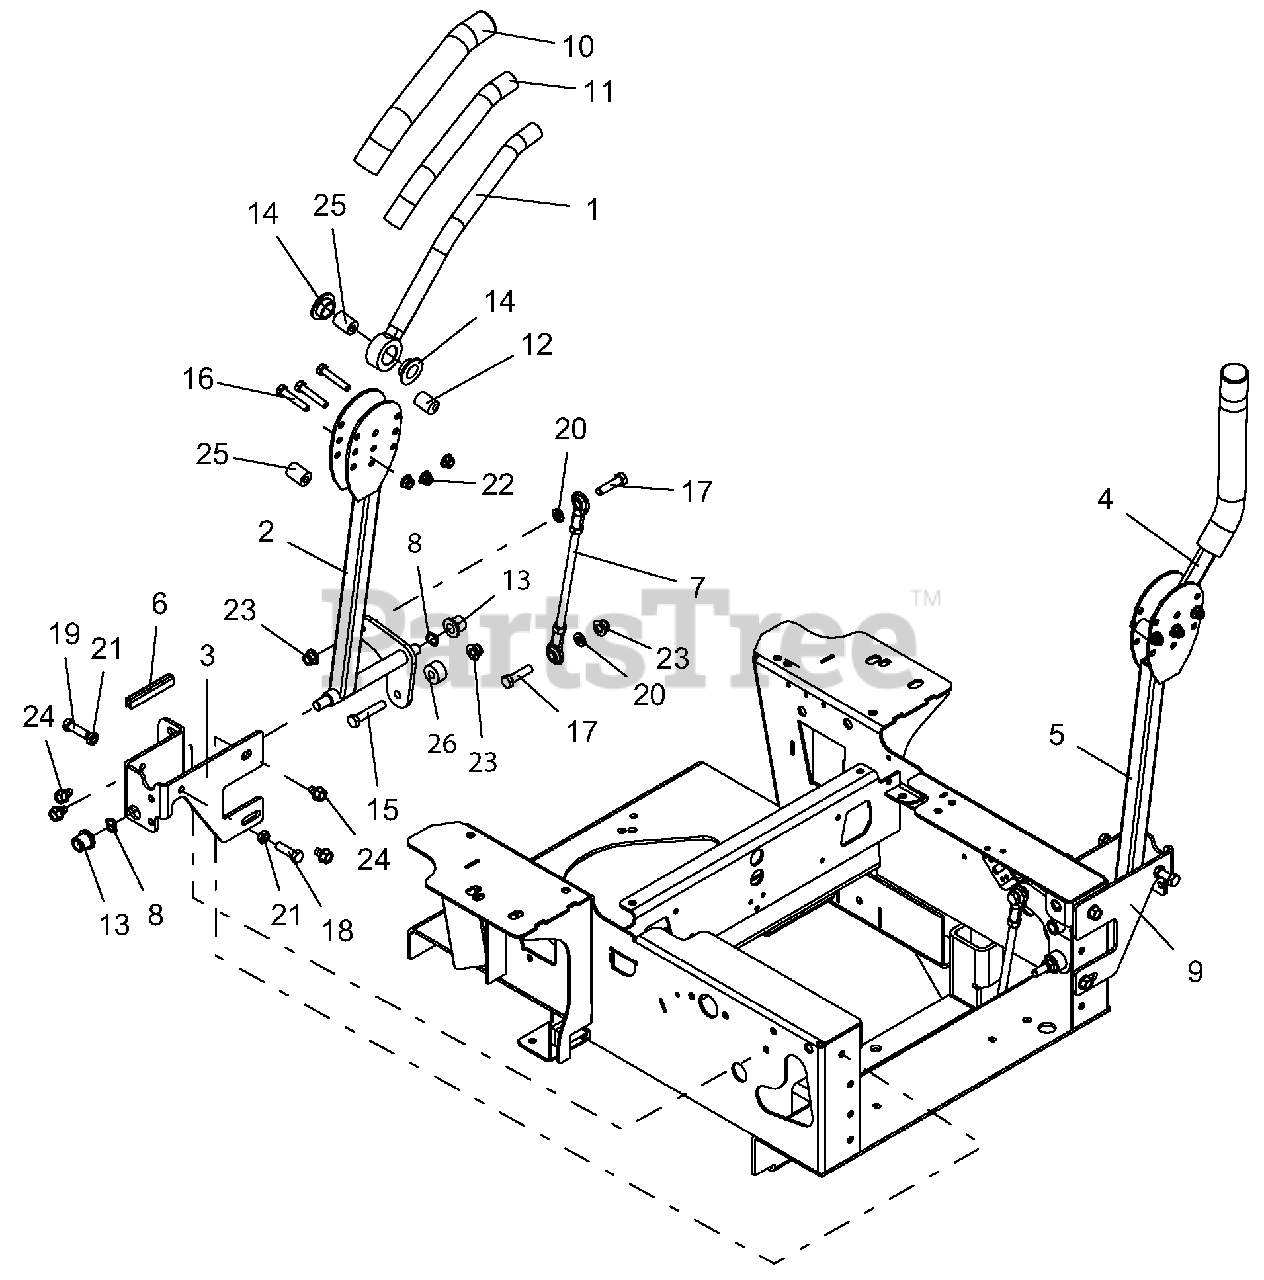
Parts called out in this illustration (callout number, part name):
1	WLDMT, RH HANDLE
2	WLDMT, PT/PT100 CONTROL ARM-BLACK
3	BRKT, RH STEERING STOP-RED
4	WLDMT, LH HANDLE
5	WLDMT, LH PT/PT100 CONTROL ARM
6	STRIP, COWL - 1.50 LG
7	ASM, STEERING LINKAGE
8	WAVE WASHER .531X.781X.125 FH
9	BRKT, LH STEERING STOP-RED
10	GRIP, HANDLEBAR
11	TUBE, .88ID X 1.00OD X 10.25
12	BSHG, ECCENTRIC .31 X .75 X .97
13	BHSG-FLG .500X.750X.750X.125
14	BSHG, FLANGE .762 X 1.48 X .44 NYLON
15	BLT-HEX .38-16X2.00 FTH GR5 YWZC
16	BLT-HEX .31-18X1.75 GR5 YWZC
17	BLT-HEX .38-16X1.50 GR5 YWZC
18	BLT-HEX .38-16X1.25 GR5 YWZC
19	BLT-HEX .38-16X1.25 GR5 YWZC
20	WSHR-LK .38X.094 REG YWZC
21	NUT, JAM .375-16 YWZC
22	NUT-LK-NYL-FLG .31-18 YWZC
23	NUT-LK-NYL-FLG .38-16 YWZC
24	SCR-TAP .38-16X.50 HWH TR YWZ
25	SPACER, .328 X .76 X 1.01
26	SPACER .390X1.000X.562
